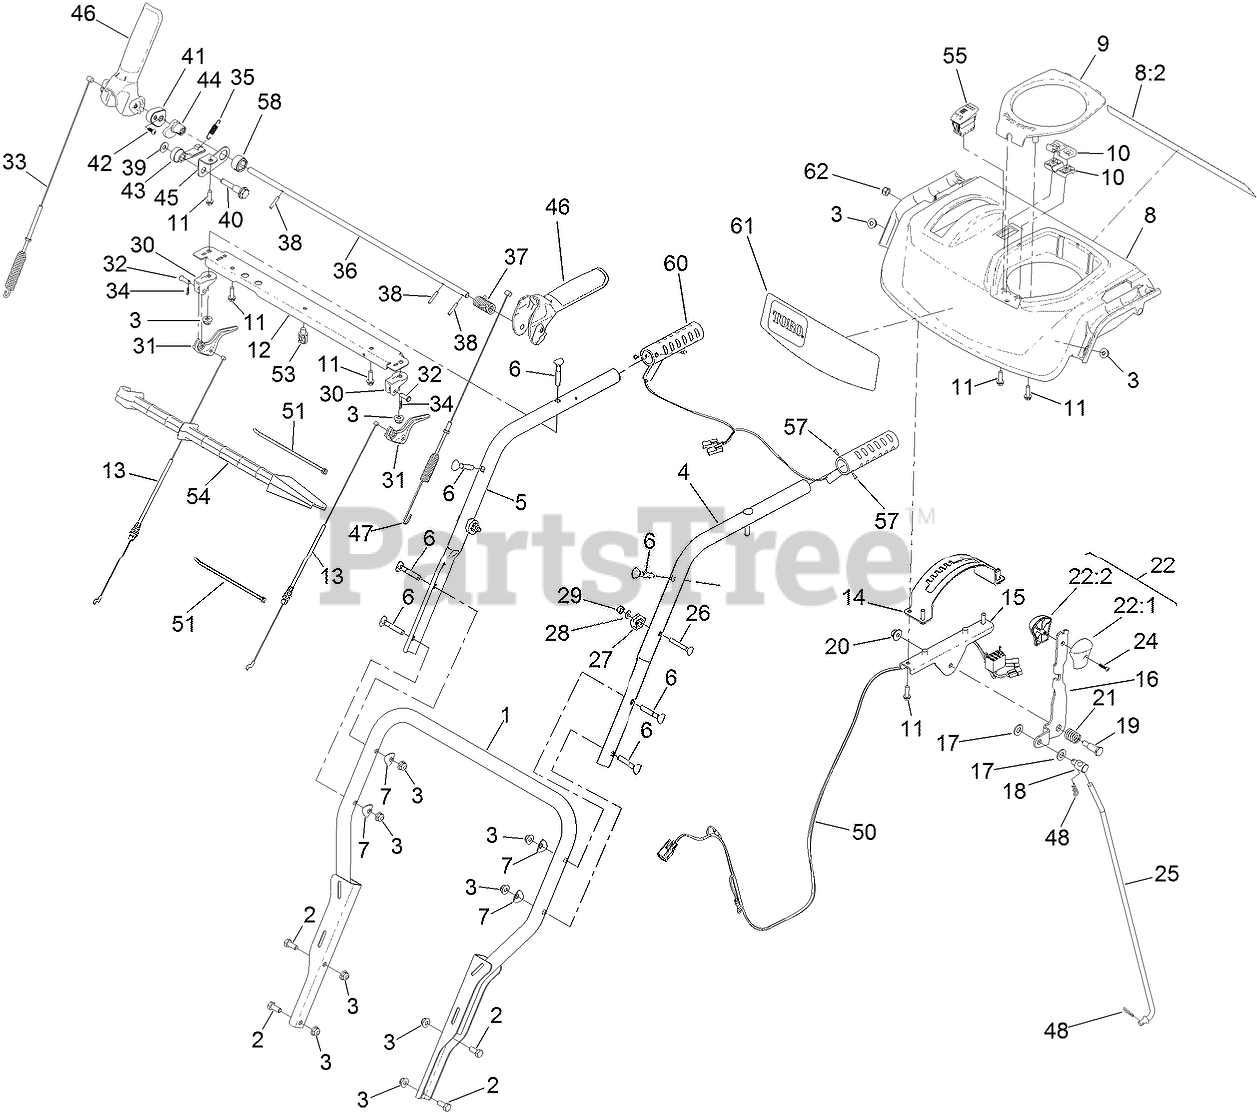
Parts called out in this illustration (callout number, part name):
1	LOWER HANDLE ASM
2	SCREW-HH
3	NUT-HF
4	HANDLE-UPPER, LH
5	HANDLE-UPPER, RH
6	SCREW-HANDLE
7	WASHER-CUP
8	PANEL-CONTROL
8:2	DECAL-SAFETY
9	COVER-QUICKSTICK
10	SUPPORT-ROD
11	SCREW-PLASTITE, HWH
12	BRACE-CONSOLE
13	CABLE-CLUTCH
14	GATE-SHIFT
15	BRACKET-SHIFT
16	SELECTOR-SPEED
17	WASHER-FLAT
18	TRUNNION-ROD
19	SCREW-SHOULDER, HH
20	NUT-HF
21	SPRING-COMPRESSION
22	SHIFT KNOB ASM
22:1	KNOB-SHIFT, LH
22:2	KNOB-SHIFT, RH
24	SCREW-PPH
25	ROD-SHIFT
26	BOLT-CARR
27	CLAMP-CABLE
28	WASHER-PLAIN
29	NUT-HEX
30	MOUNT-LEVER, CLUTCH
31	LEVER-CLUTCH
32	PIN-CLEVIS
33	CABLE-AUGER
34	PIN-HAIR
35	SPRING-LOCKOUT, HANDLE
36	ROD-LOCKOUT
37	SPRING-TORSION, HANDLE RETURN
38	PIN-SPRING
39	WASHER-FLAT
40	SCREW-SHOULDER
41	LOCK-HANDLE
42	SCREW-PPH
43	LATCH-LOCKOUT
44	CAM-LOCKOUT
45	LINK-LOCKOUT
46	LEVER-CONTROL
47	CABLE-TRACTION
48	PIN-HAIR
50	HARNESS-WIRE, LED AND HAND WARMERS
51	TIE-CABLE
53	CLIP-TIE
54	STICK-CLEANOUT
55	SWITCH-ROCKER, ON-NONE-OFF (HEATER)
57	RIVET-POP
58	COLLAR-CAM
60	GRIP-HEATED
61	DECAL-CONSOLE
62	NUT-HEX
